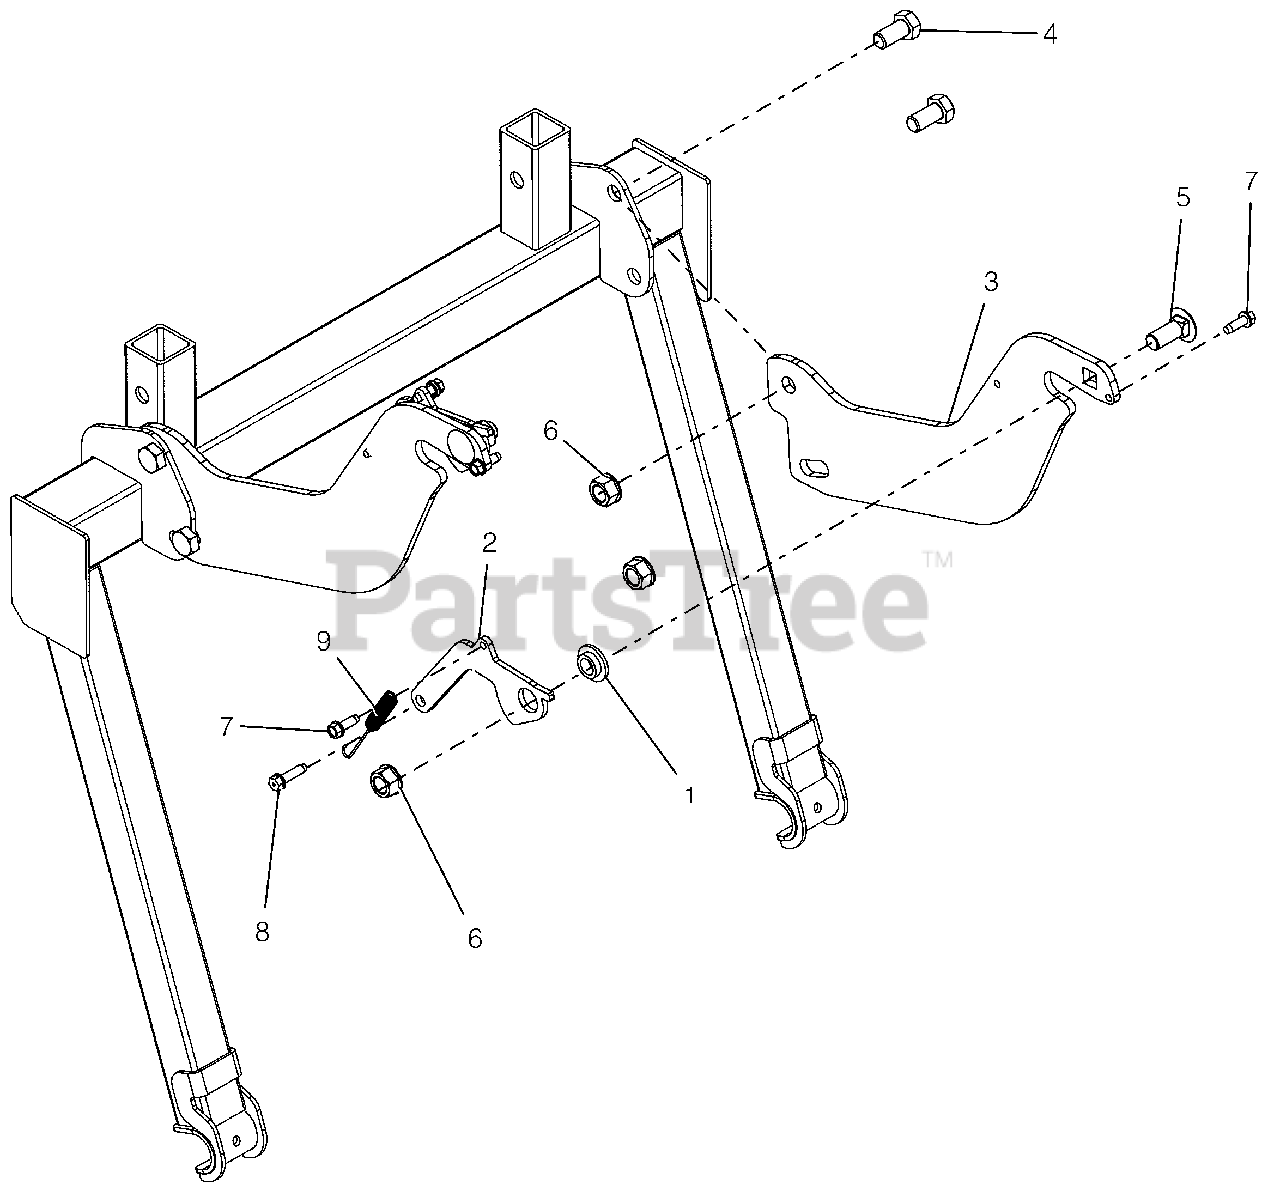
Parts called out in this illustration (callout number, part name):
1	BSHG-FLG .515X.750X.310X1.120
2	BAGGER, LATCH - BLACK
3	LATCH, BAGGER MTG ARMS
4	@BLT-HEX .50-13X1.00 GR5 YWZC
5	@BLT-RDHDSQNK .50-13X1.25 G5YZ
6	@NUT-LK-TOP-FLG .50-13 YWZC
7	SCR-TAP-PM .25-20X.75 TR YWZ
8	@SCR-TAP .25-20X1.00 HWH TR YZ
9	SG-TENS .043X.44X3.31 WLD 5.8
